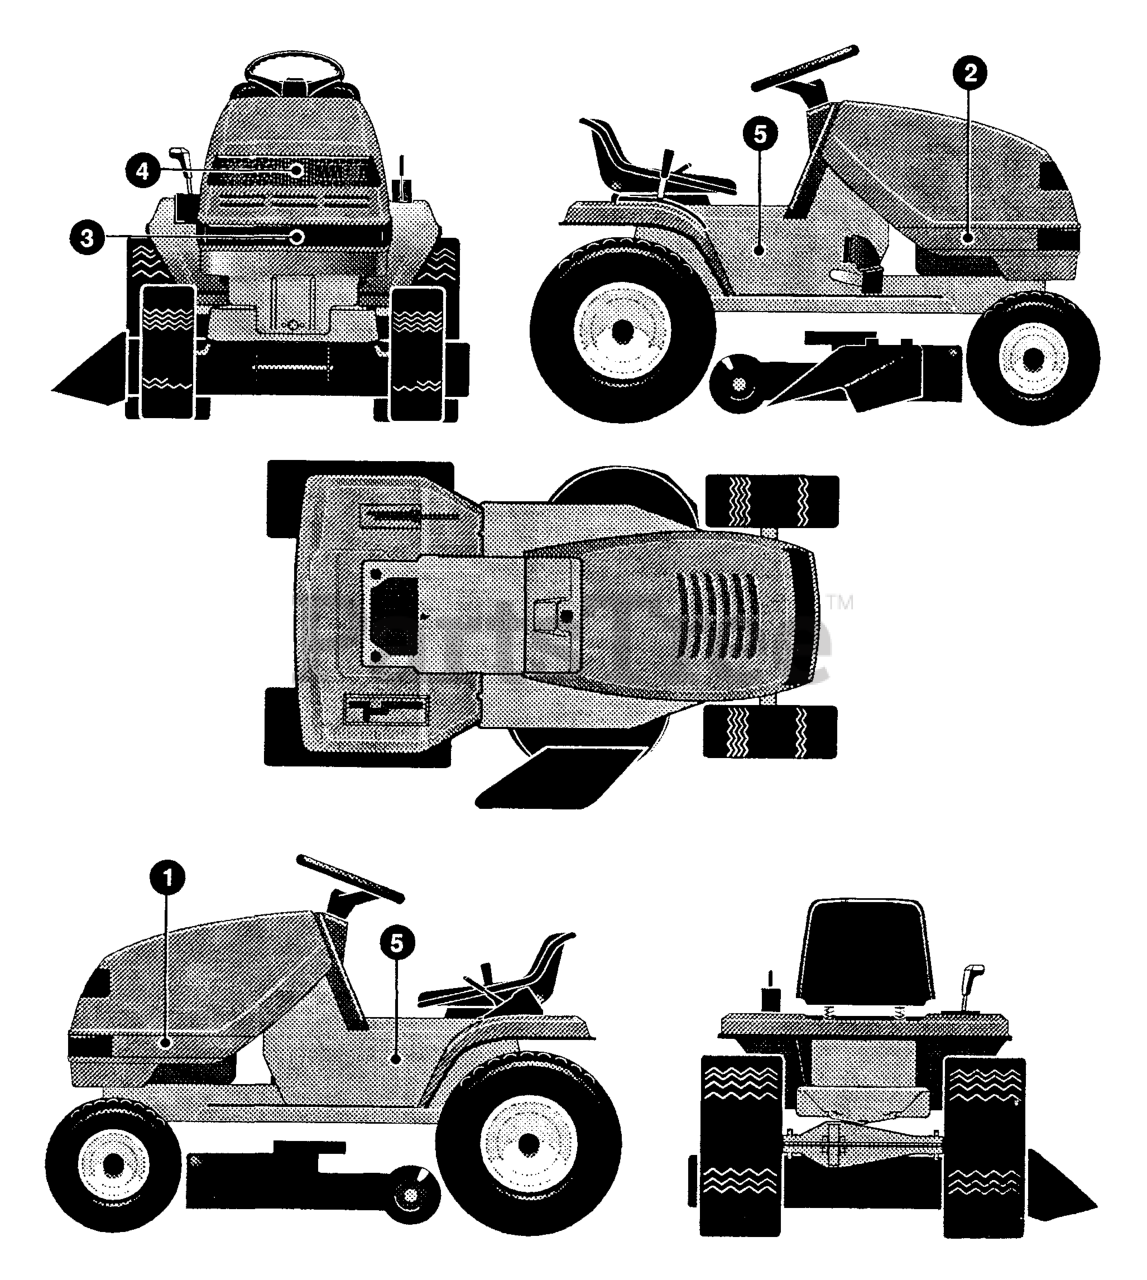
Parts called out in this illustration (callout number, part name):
1	DECAL, HOOD-RH
2	DECAL, HOOD-LH
3	DECAL, TAPE H13
4	FOIL, LENS HOOD REFLECTOR
5	NAMEPLATE 12.5/40 WHITE
